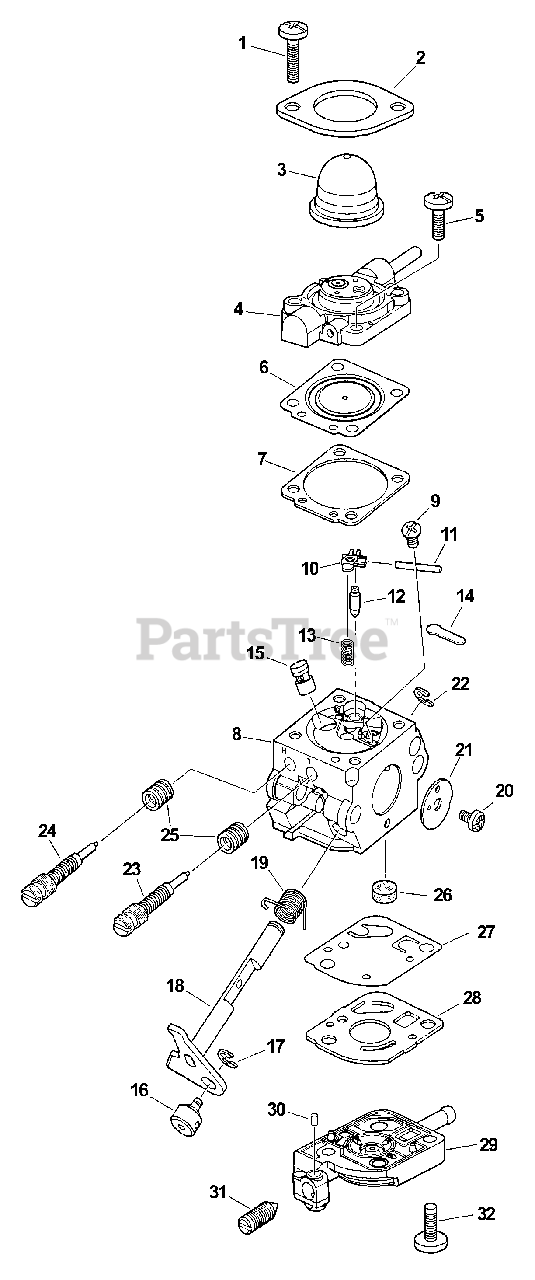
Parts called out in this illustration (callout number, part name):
1	SCREW, PURGE BASE
2	RETAINER, PURGE BULB
3	BULB, PURGE
4	BASE, PURGE
5	SCREW, RETAINER
6	DIAPHRAGM, METERING
7	GASKET, METERING
8	BODY, CARBURETOR
9	SCREW, METERING LEVER PIN
10	LEVER, METERING
11	PIN, METERING LEVER
12	VALVE, INLET NEEDLE
13	SPRING, METERING LEVER
14	PLUG, WELCH
15	NOZZLE, CHECK VALVE
17	RING, RETAINING
18	SHAFT, THROTTLE
19	SPRING, RETURN
21	VALVE, THROTTLE
22	RING, RETAINING
23	NEEDLE - MIXTURE
24	NEEDLE - HIGH SPEED
26	STRAINER
27	DIAPHRAGM, PURGE
28	GASKET, PURGE
29	BASE, PURGE
30	PIECE, FRICTION
31	SCREW, IDLE ADJUST
32	SCREW, PUMP COVER
